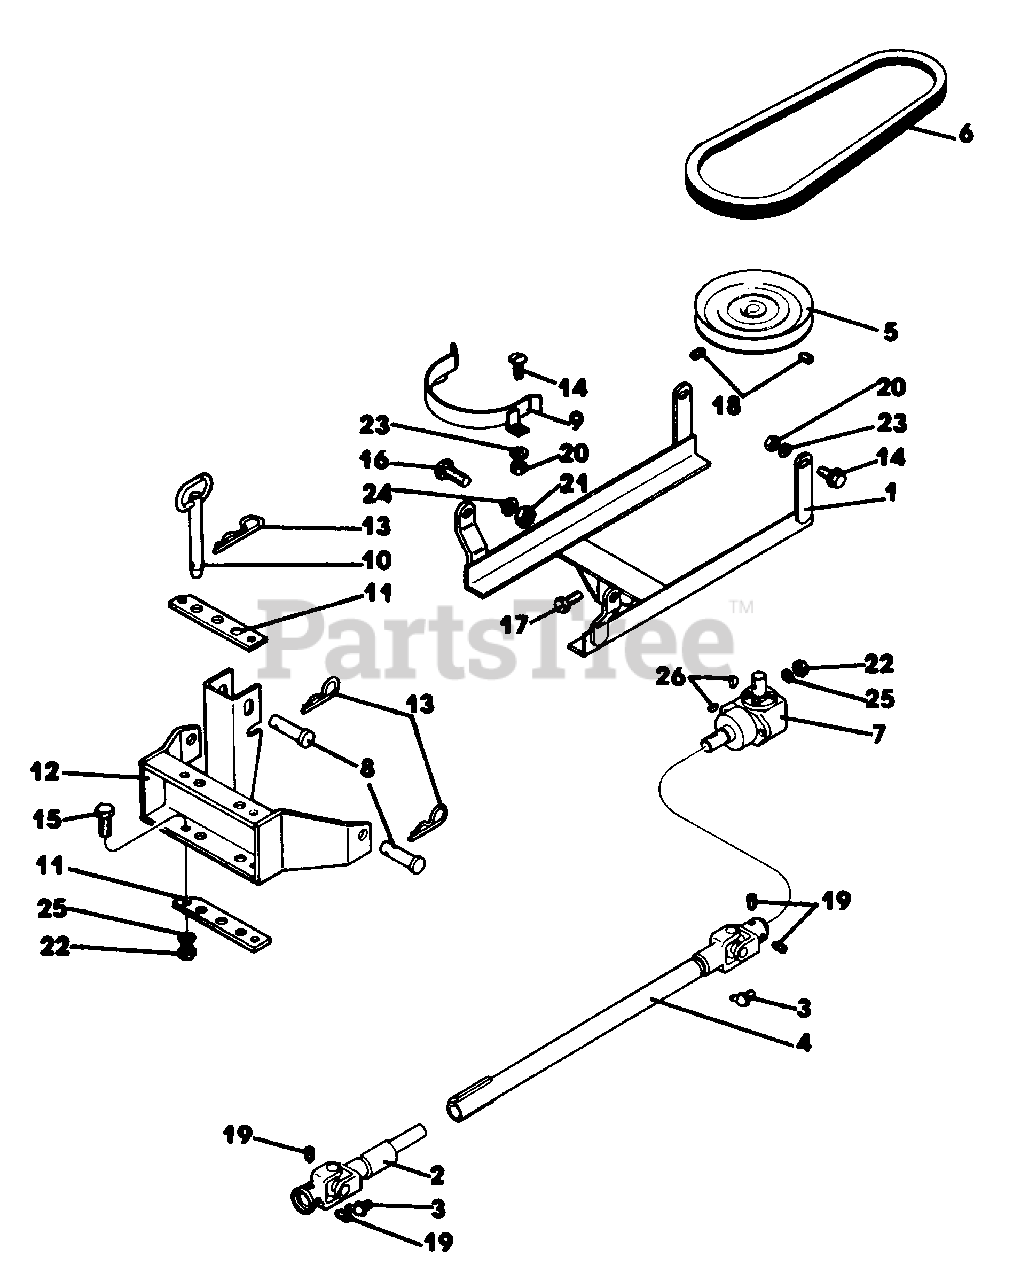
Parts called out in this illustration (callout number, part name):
1	Support Assembly-P.T.O.
2	Assembly-Universal Joint
3	Grease Fitting
4	Assembly-Drive Tube
5	Pulley-7"
6	V-Belt
7	Gear Box
8	Clevis Pin
9	Guard Assembly-Belt
10	Hitch Pin
11	Wear Plate
12	Assembly-Hitch Plate
13	Spring Clip
14	Machine Screw Round Hd. #10-24 x 1" Plated
15	Cap Screw, Hex Hd. 3/8-16 x 1-1/4 Plated, Grade 5
16	Cap Screw, Hex Hd. 5/8-11 x 1-1/4 Plated, Grade 5
17	Cap Screw, Hex Hd. 3/8-16 x 1-1/8 Plated, Grade 5
18	Set Screw, Hex Socket Hd. Cup Pt. 5/16-18 x 5/16
19	Set Screw, Hex Socket Hd. Cup Pt. 3/8-16 x 3/8
20	Nut, Hex #10-24 Plated
21	Nut, Hex 5/8-11 Plated
22	Nut, Hex 3/8-16 Plated
23	Washer, Spring Lock #10 Plated
24	Washer, Spring Lock 5/8 Plated
25	Washer, Spring Lock 3/8 Plated
26	Key, Woodruff 3/16 x 3/4
